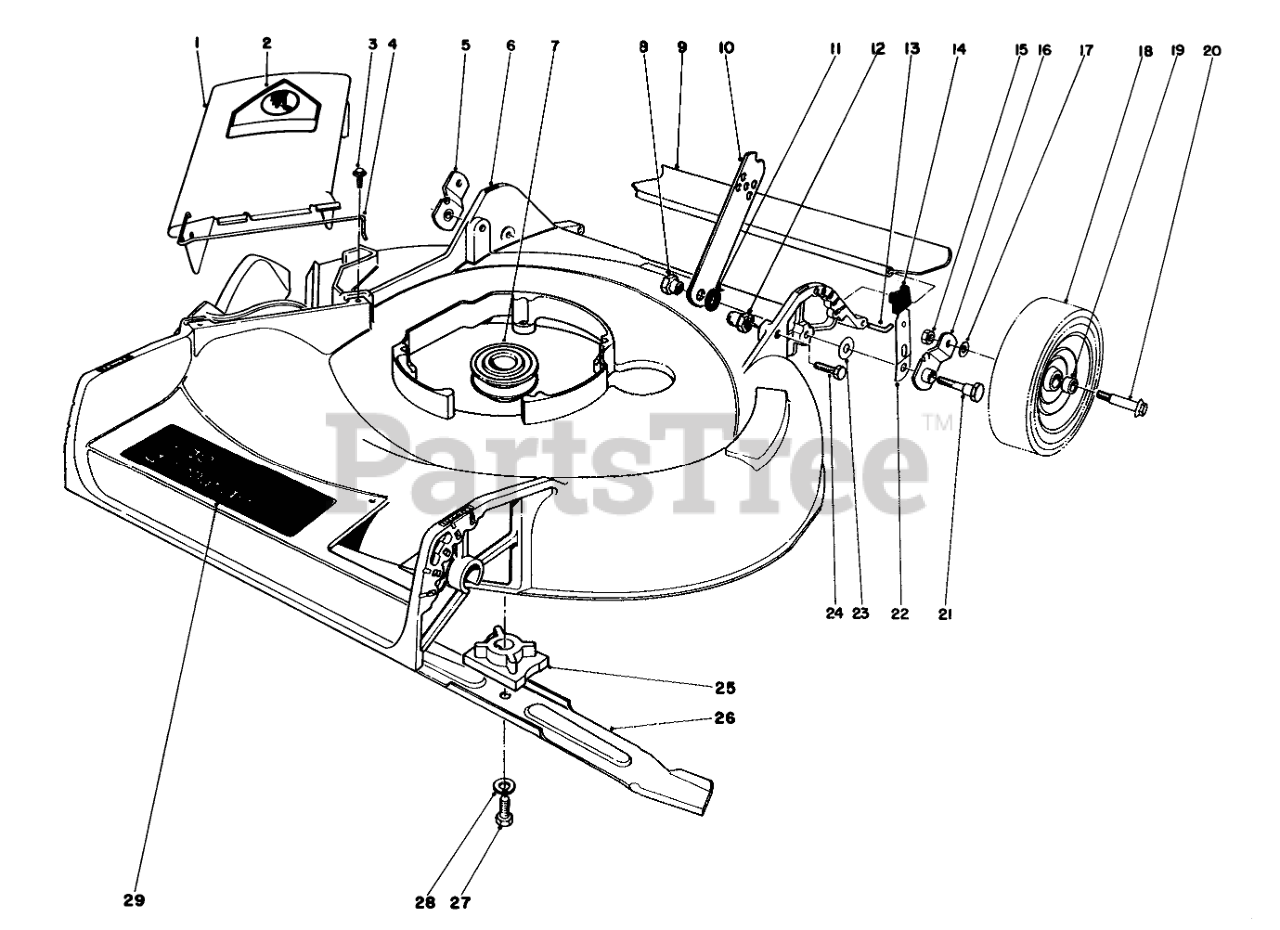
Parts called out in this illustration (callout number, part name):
1	Deflector Assembly (Incl. Ref. #2 & 4)
2	DECAL-DANGER
3	SCREW-HWH
4	SPRING HINGE
5	Pivot Arm
6	Housing
7	PULLEY-DRIVER
8	HANDLE PIVOT NUT
9	REAR SAFETY SHIELD 21
10	HANDLE LATCH
11	SPACER
12	HANDLE PIVOT NUT
13	SHIELD ROD
14	KNOB-ARM
15	NUT-LOCK
16	Pivot Arm
17	WASHER
18	Wheel & Tire Assembly (Incl. Ref. #19)
19	BUSHING
20	WHEEL BOLT
21	PIVOT SCREW
22	SPRING ARM ASM
23	WASHER-PIVOT
24	SCREW-HH
25	BLADE RETAINER
26	Blade
27	SCREW-HH
28	WASHER-LOCK
29	Decal-Side Discharge
